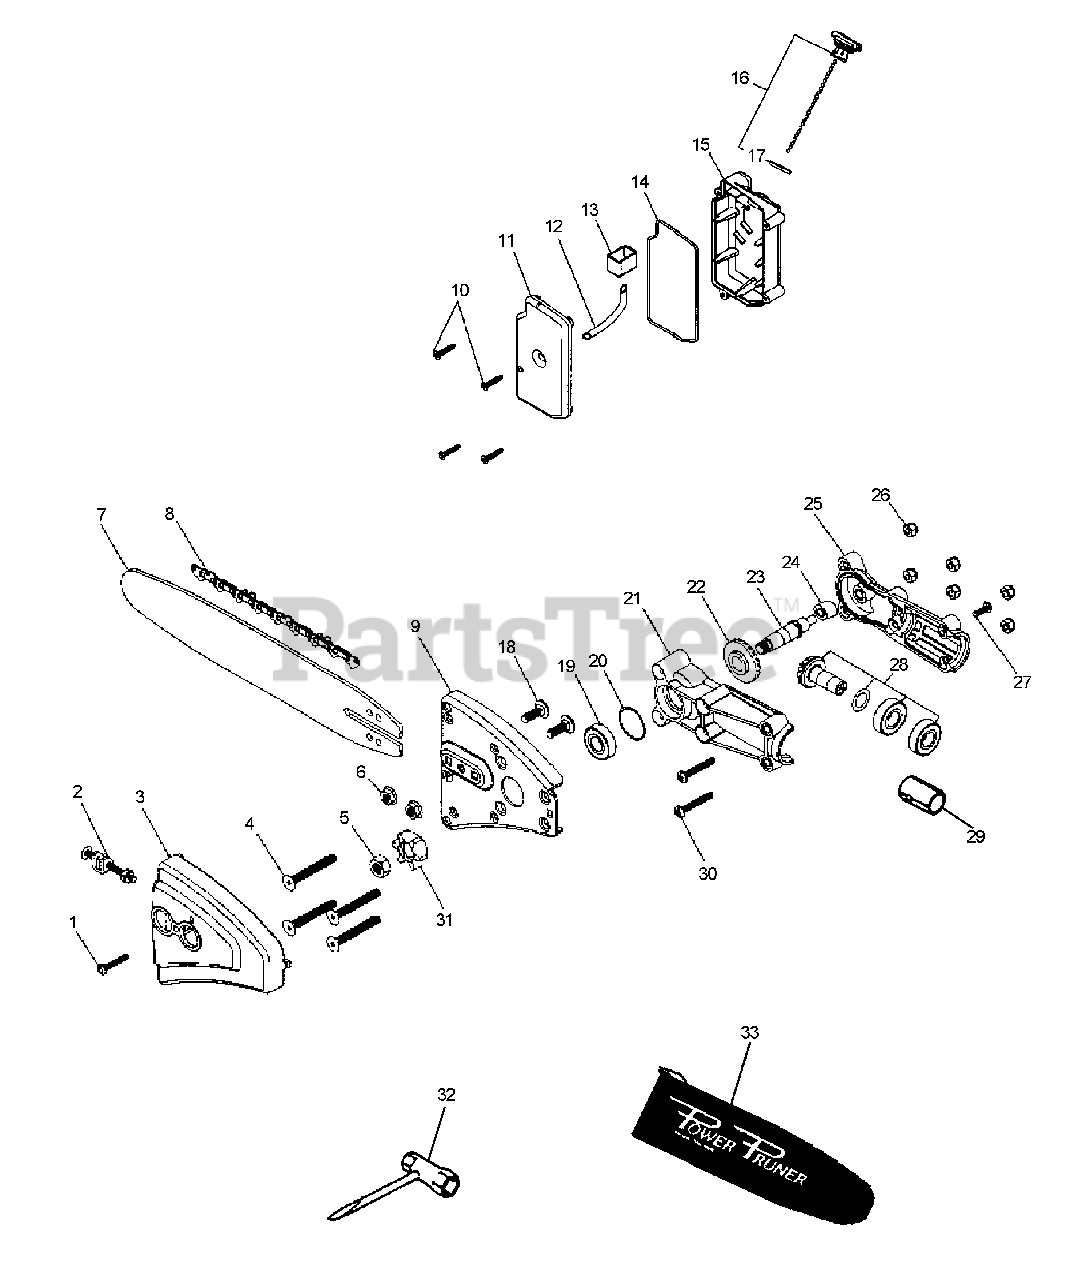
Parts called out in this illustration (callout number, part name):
1	SCREW - 8-32 X 1"
2	TENSIONER KIT
3	GUARD, SPROCKET
6	NUT - FLANGE
7	GUIDE BAR - 12" (30cm)
8	SAW CHAIN - 12" (30cm)
9	SAW BAR CARRIER
10	SCREW
11	TANK, OIL (CHAIN SIDE)
12	PIPE - 3X5X70 -- BLACK
13	CUP, OIL
15	TANK, OIL (CAP SIDE)
16	CAP ASSY
18	BOLT
19	BEARING, BALL - 6001 DDU
20	SHIM .004"
21	CASE, GEAR - RIGHT
22	GEAR - BEVEL
23	SHAFT GEAR ASSY
24	GUIDE, DRIVESHAFT
25	CASE, GEAR - RIGHT
26	LOCKNUT - 10-24
27	SCREW
28	SHAFT GEAR ASSY
29	COLLAR - 22
30	SCREW - 10-24 X 1-1/4"
31	SPROCKET
32	T-WRENCH
33	COVER, GUIDE BAR - 12" (30cm)
